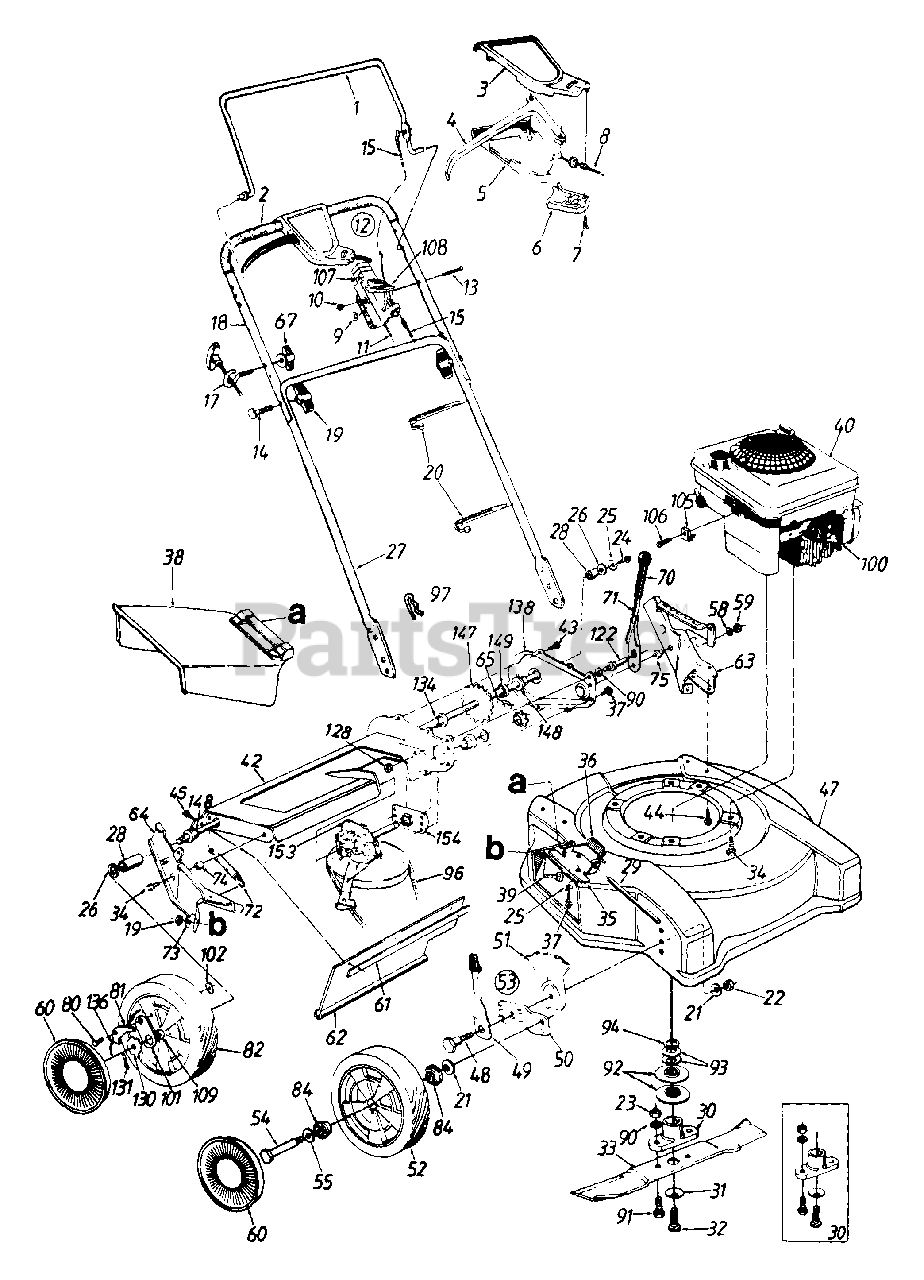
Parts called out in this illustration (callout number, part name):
1	Control Handle Ass'y. (Std.)
2	Foam Grip
3	Upper - S.P. Control Cover
4	Control Lever
5	Lower - S P. Control Cover
6	S.P. Control Cover
7	Fl-"C"-Sunk Hd. Tap Scr. #1O x .75" Lg.
8	S P. Adj, Cable - 48" Lg.
9	Spr. Wash..66" I.D.
10	Hex L-Nut 1/4-20 Thd.
11	Throttle Control Wire - 55"
12	Throttle Box Comp.
13	Oval C-Sunk Scr.
14	Curved Hd. Bolt 5/16-18 x 2"
15	Control Cable 39" Lg.
17	Rope Guide
18	Upper Handle
19	Hand Knob
20	Cable Tie
21	Bell-Wash..38" I.D. x.88"
22	Hex Nut 3/8-16 Thd.
23	Hex Nut 3/8-24 Thd.
24	Hex Bolt 1/4-20 x .62" Lg. (Grade 5)
25	Bell-Wash. 1/4" I.D.
26	Fl-Wash..531" I.D. x .93"
28	Spacer .513" I.D. x .703"
29	Hinge Pin
30	Blade Adapter Kit
31	Bell-Wash..46" I.D.
32	Hex Bolt 7/16-20 x 1.5" Lg.
33	22" Blade
34	Hex L-Wash. Hd. Scr. 3/8-16 x 1.0" Lg.
35	Adapter Plate
36	Torsion Spring
37	Hex Self-Tap Scr. 1/4-20 x .5"
38	Chute Deflector Ass'y.
39	Carriage Bolt 5/16-18 x .62" Lg.
40	Engine
41	Cable Clamp
44	Hex Wash. Hd. B-Tap Scr. 5/16-18
45	Hex AB-Tap Scr. 1/4 x .62"
46	Hex B-Tap Scr. #10 x .38"
49	Spring Lever Ass'y. w/Knob
51	Height Adj. Plate
52	Front Wheel Ass'y. Comp.
53	Height Adj Ass'y Comp - R.H.
53	Height Adj. Ass'y. Comp.- L.H.
54	Shld. Bolt .498" Dia. x 1.45"
55	Wave Wash. 51" I.D. x .78"
56	Cable Clamp
57	Hex B-Tap Scr #10 x .62"
58	Fl-Wash 385" I.D. x .87"
59	Hex Patch L-Nut 3/8-24 Thd.
60	Hub Cap
61	Retaining Strip
62	Rear Flap
63	L.H. Handle Wheel Brkt. Ass'y.
64	R.H. Handle Wheel Brkt. Ass'y.
65	#48 Chain .5" Pitch x 30 Links
67	Wing Nut 1/4-20 Thd.
71	Height Adj. Lever
72	Ext. Spring .5" O.D. x 3.8" Lg.
73	Bell-Wash. 5/16" I.D.
74	Spacer .383" I.D. x .503"
75	Shld. Spacer .5" Dia.
80	Shld. Scr..342" Dia. x 268"
82	Rear Wheel Ass'y. Comp.
84	Ball Bearing 1/2" I.D.
90	L-Wash. 3/8" I.D.
91	Hex Bolt 3/8-24 x 1.0" Lg.
92	Splined Pulley Half
93	Bell-Wash. 1.01" I.D.
94	Crankshaft Spacer
96	V-Belt
97	Hairpin Clip
100	Spark Plug Boot
101	Pawl Plate
102	Weld L-Nut 1/4-20 Thd.
105	Cable Clamp
106	Hex Self-Tap Scr. #10-32 x .62"
107	Throttle Body
108	Throttle Lever
109	Sleeve Brg. 1/2" I.D.
122	Shld. Pin 3/8-24 x 1.43" Lg.
128	Hex Jam Nut 3/8-24 Thd.
130	Ratchet Wheel 1.62" O.D.
131	Cotter Pin 1/8" Dia.
134	Hex Flange Bearing
136	Spring - Nylon
148	Hex Flange Bearing
149	Fl-Wash..531" I.D. x .93"
153	Transmission Comp. (See Breakdown)
154	Hex Bearing Cup
